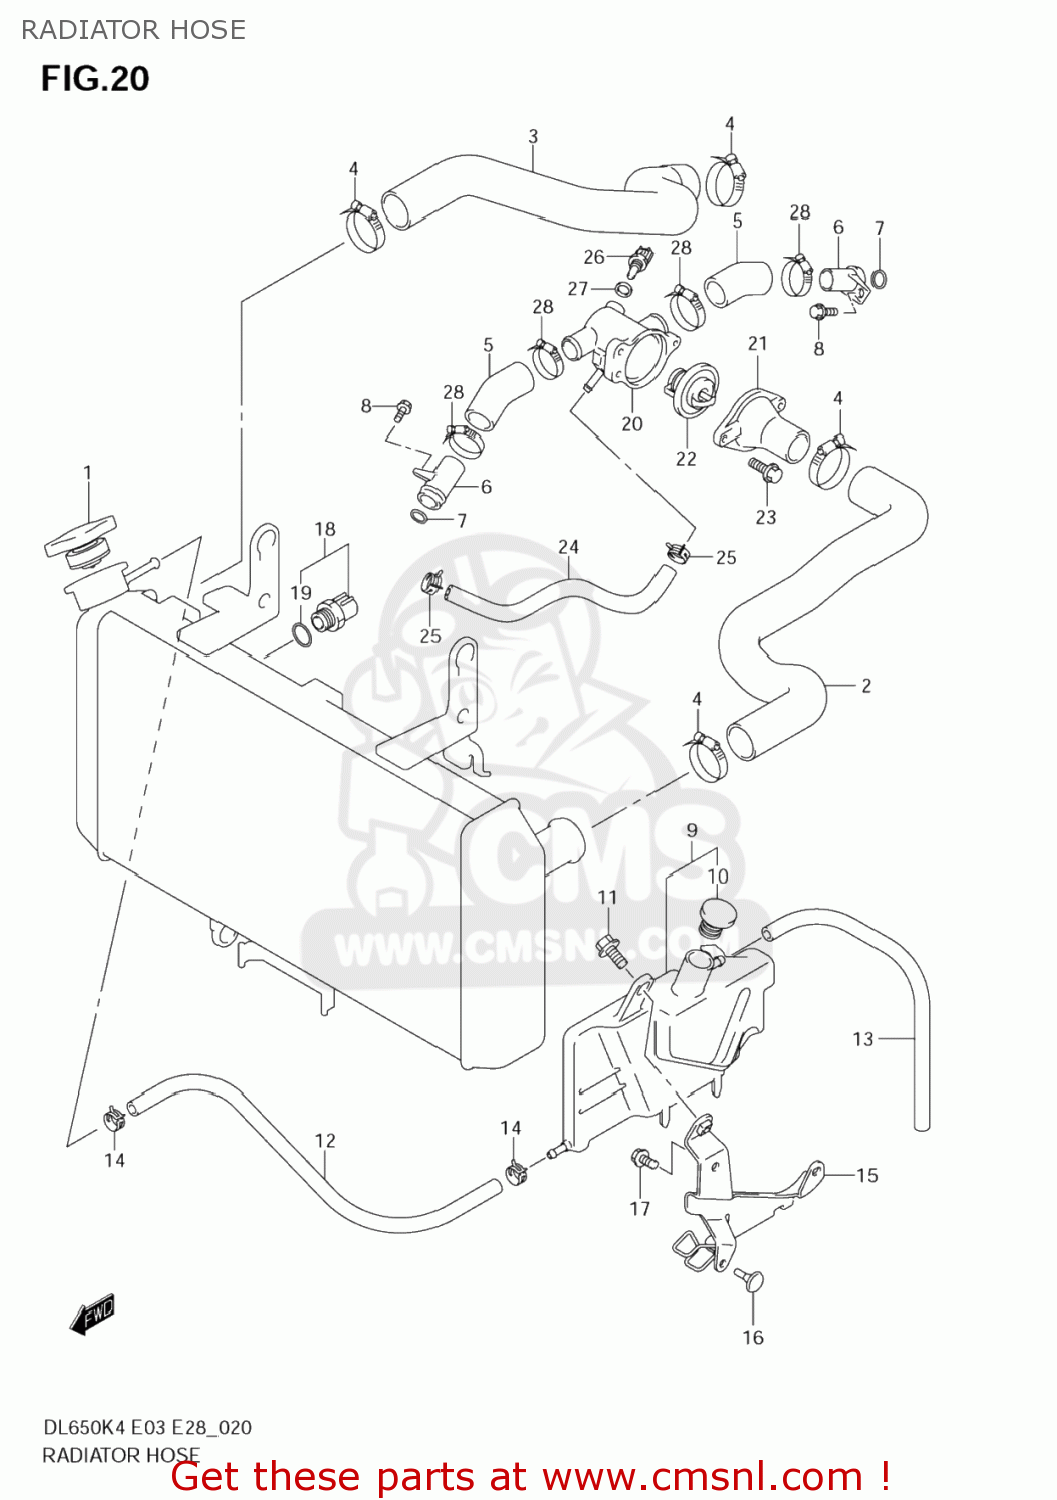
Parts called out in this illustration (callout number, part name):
1	CAP COMP,RADIATOR
2	HOSE,RADIATOR INLET
3	HOSE,RADIATOR OUTLET
4	CLAMP
5	HOSE,CONNECTOR INLET
6	UNION,CONN HOS
7	O RING(D:3.2,ID:17.8)
8	BOLT,STRANGER
9	TANK ASSY,RESERVOIR
10	CAP,RESERVOIR TANK
11	BOLT(6X12)
12	HOSE(5X9X2000)
13	HOSE(5X9X2000)
14	CLIP
15	BRACKET,RESERVOIR TANK
16	CUSHION
17	BOLT
18	SWITCH,FAN THERMO
19	O-RING
20	CONNECTOR,THERMOSTAT INLET
21	CAP,THERMOSTAT CONNECTOR
22	THERMOSTAT,WATER
23	BOLT
24	HOSE,CONNECTOR TO WATER PUMP
25	CLAMP
26	SENSOR,WATER TEMP
27	GASKET(12X17X1) (NAS)
28	CLAMP
